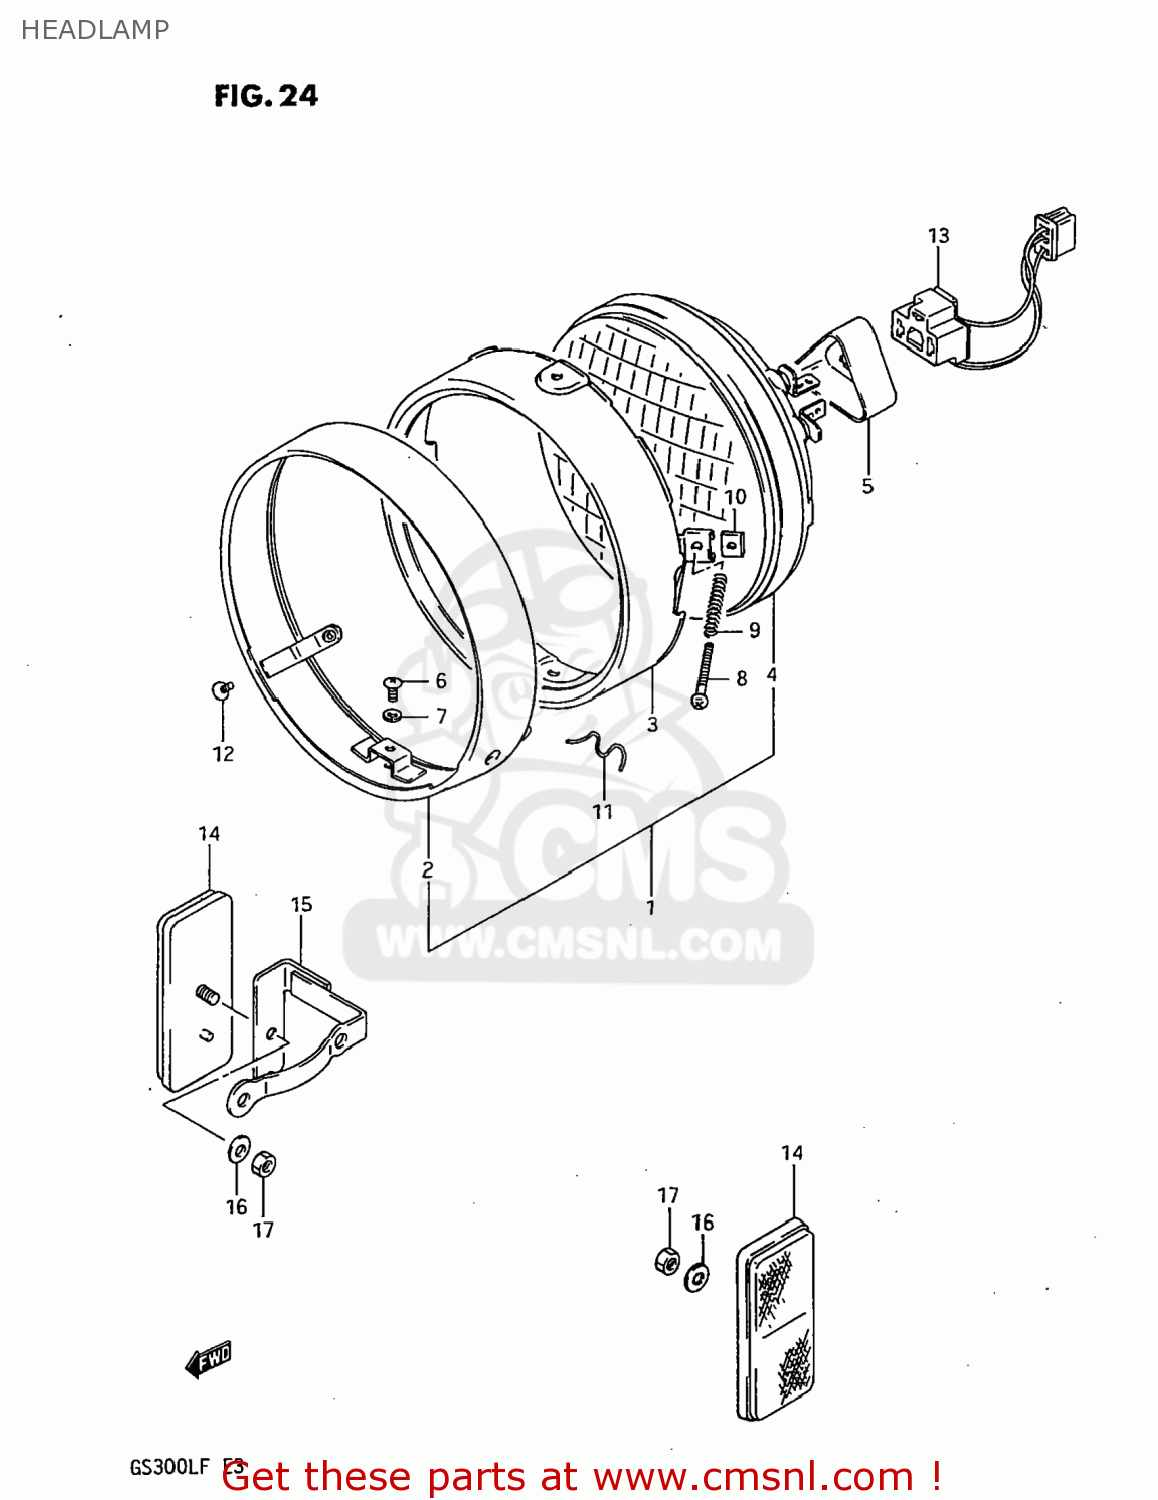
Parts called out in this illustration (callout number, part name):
1	LAMP ASSEMBLY,HEAD
2	RIM
3	RETAINER
4	LAMP UNIT
5	COVER
6	SCREW
7	LOCK WASHER
8	SCREW
9	SPRING
10	NUT
11	SPRING,HEAD LAMP UNIT
12	SCREW(5X12)
13	LEAD WIRE,HEADLAMP
14	REFLEX REFLECTOR,FR SIDE
15	BRACKET,FRONT SIDE,REAR,RIGHT
16	WASHER,5MM
17	NUT ,5MM
